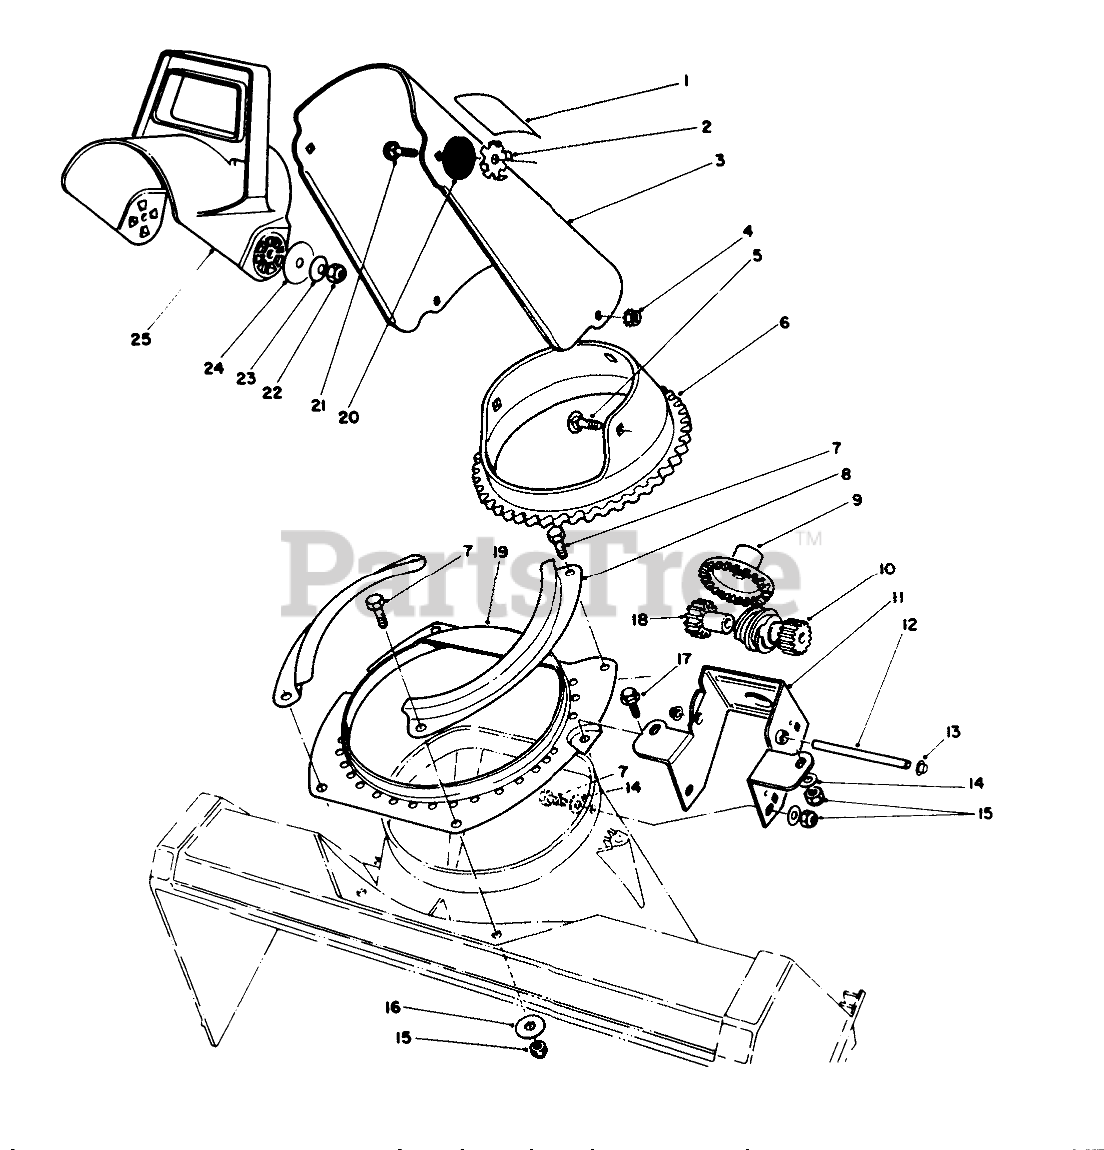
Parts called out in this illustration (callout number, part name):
1	Decal-Danger
2	PLATE-FRICTION
3	Chute-Discharge (Incl. Ref. #1: 63-3760)
4	NUT-KEPS
5	SCREW-CARR
6	RING-GEAR, CHUTE
7	SCREW-HH
8	Retainer-Chute Ring
9	GEAR-FACE
10	GEAR-SPUR/WORM
11	Bracket-Chute Gear
12	SHAFT-GEAR, WORM
13	NUT-PUSH
14	WASHER-FLAT
15	NUT-LOCK, NI
16	WASHER-FLAT
17	SCREW-PLASTITE
18	GEAR-SPUR, SPACER
19	Ring-Chute Support
20	WASHER-RUBBER
21	SCREW-CARR
22	NUT-LOCK, NI
23	WASHER-BELLEVILLE
24	WASHER-FLAT
25	CHUTE-DEFLECTOR
